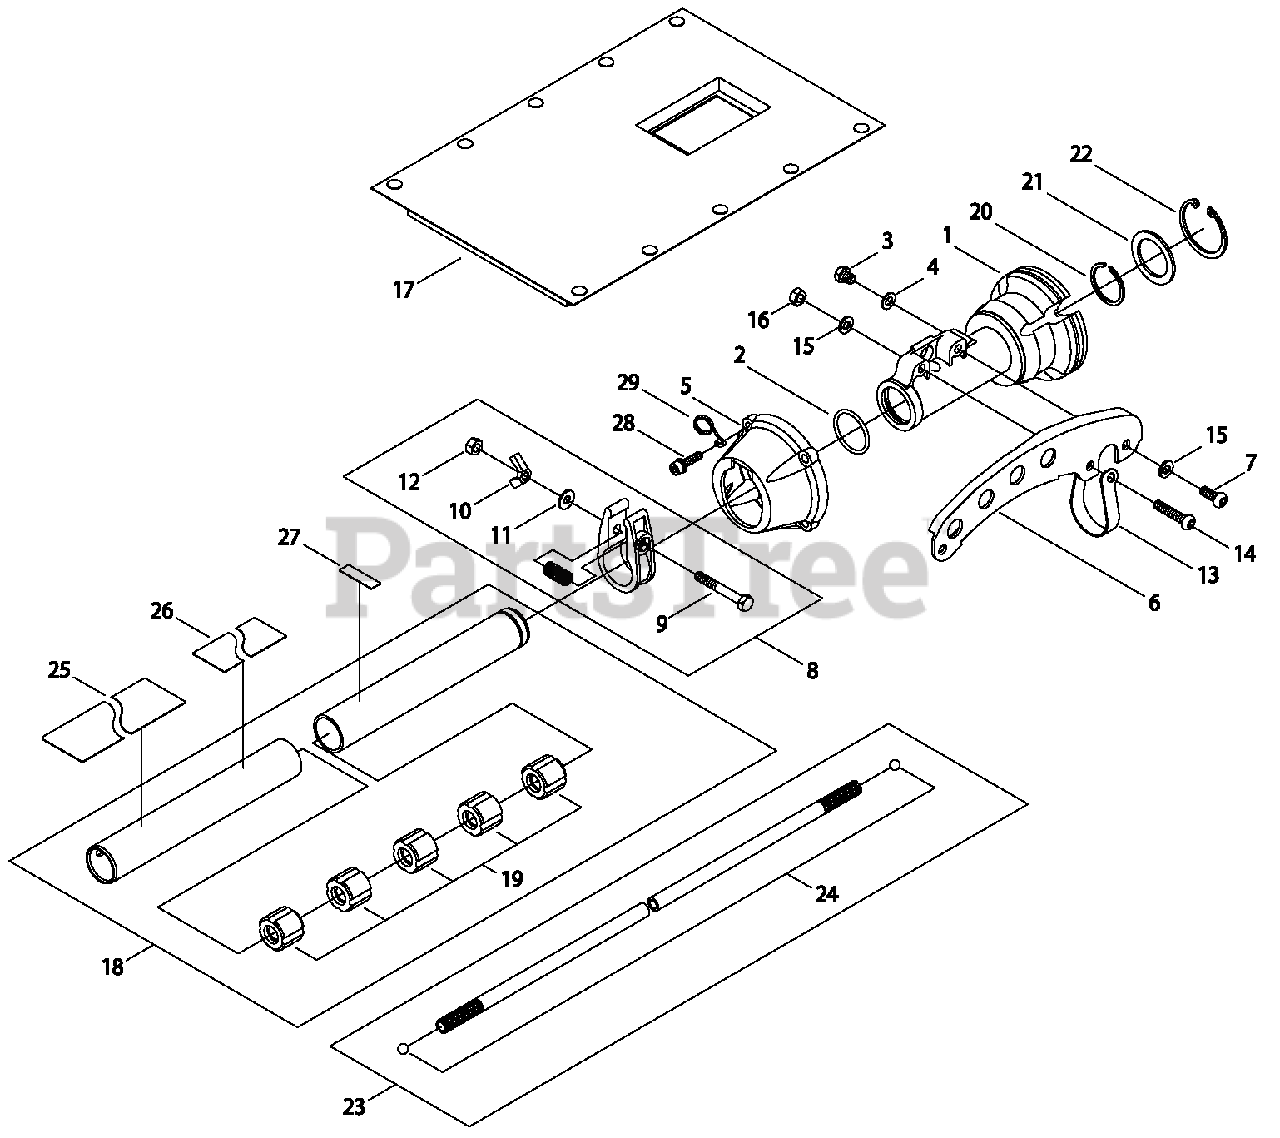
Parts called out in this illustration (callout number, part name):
1	CUSHION, AV
2	O-RING
3	BOLT M6×8
4	WASHER
5	CAP, CUSHION
6	HANGER
7	BOLT M6×16
8	SWIVEL ASSY
9	BOLT
10	NUT, WING M6
11	WASHER 6 MM
12	NUT, LOCK M6
13	CLAMP
14	BOLT M6×30
15	WASHER, SPRING 6
16	NUT, HEX M6
17	PROTECTOR
18	MAIN PIPE ASSY
19	BUSHING
20	RING, SNAP
21	STOPPER
22	RING, SNAP Ø40
23	DRIVESHAFT ASSY
24	STOPPER
25	LABEL, SHINDAIWA PROFESSIONAL
26	LABEL, CAUTION (BLADE CAPABLE)
27	LABEL, HANDLE
28	BOLT M5×20
29	HOLDER, CABLE
